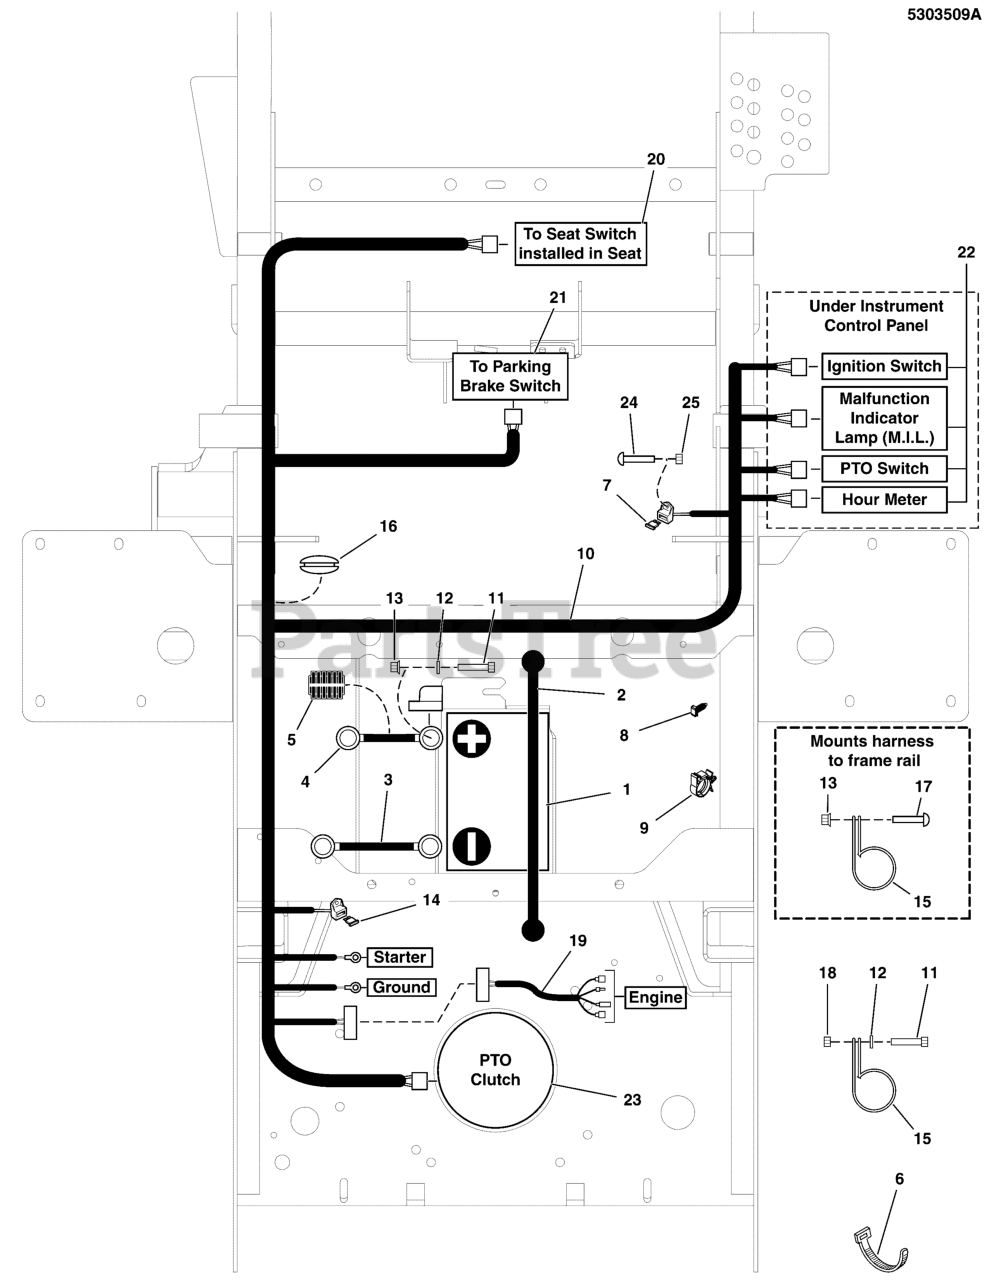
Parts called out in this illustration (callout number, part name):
1	BATTERY, 11U1L, 350 CCA
2	STRAP, BATTERY, 14 LONG, Rubber
3	BATTERY CABLE, NEG, 22, 1/4-5/16
4	BATTERY CABLE, POS, 22, 1/4-5/16
5	WIRE LOOM, 3/8 ID X 16 IN
6	TIE, SELF-LOCKING, 12"
7	FUSE, ATO, 25 AMP
8	FIR TREE MOUNT, PACKARD
9	ROSEBUD LOOM CLIP
10	WIRE HARNESS, MAIN, LG, ZTR
10	HARNESS, Wiring, Large ZTR
11	BOLT, 1/4"-20 X 3/4" GD5 YZ
12	WASHER, 1/4 SAE
13	NUT, 1/4-20 HEX SERR. FLANGE
14	FUSE, ATO-15 (15 AMP)(SV)
15	CLAMP, VINYL INSULATED, 1.00
16	GROMMET, 1-1/2" ID FOR 1/4" METAL
17	SCREW, 1/4-20 X 1, ALLEN BH, CZ
18	NUT, 1/4-20 Hex Nylock Flange
19	WIRE HARNESS, JUMPER, KAWI - LARGE HARNE
20	Refer to: Seat Mount & Floor Group
21	Refer to: Parking Brake Group
22	Refer to: Engine & PTO Group
23	Refer to: Instrument Control Panel Group
24	SCREW, #10-24 X 1/2" ROUND PHILLIPS
25	NUT, Hex, Nylon Lock, #10-24
